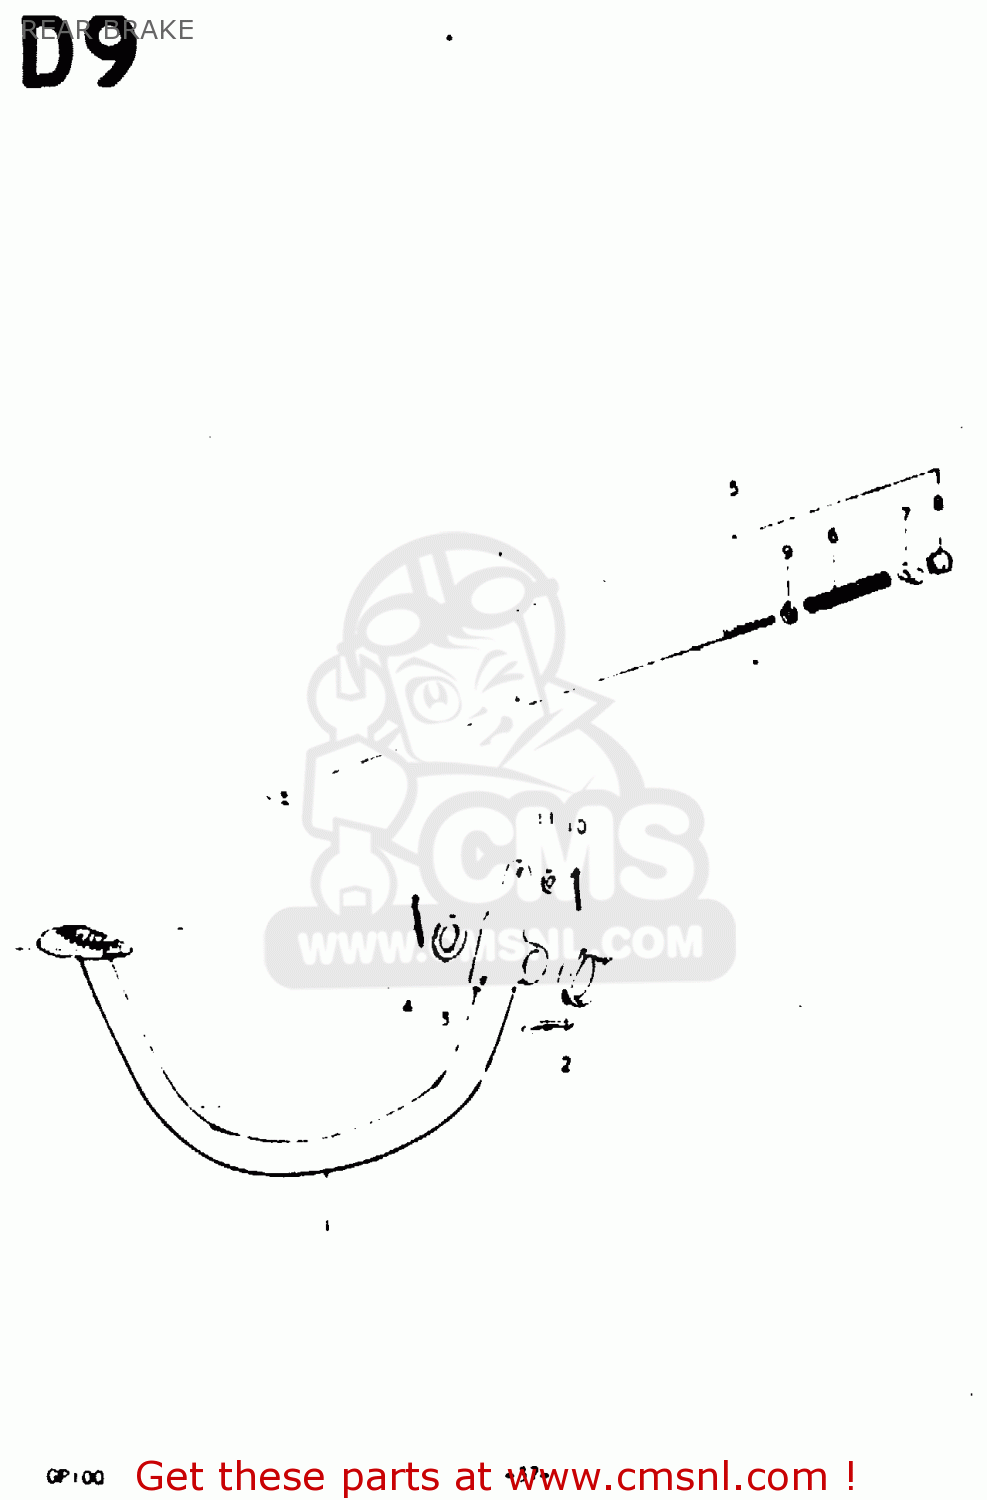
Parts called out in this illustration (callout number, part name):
1	PEDAL,BRAKE
2	SPRING
3	WASHER(15.5X26X2.3)
4	COTTER PIN
5	ROD ASSY, REAR BRAKE
6	SPRING
7	PIN(11X18)
8	NUT
9	WASHER
10	PIN 20X20
11	WASHER
